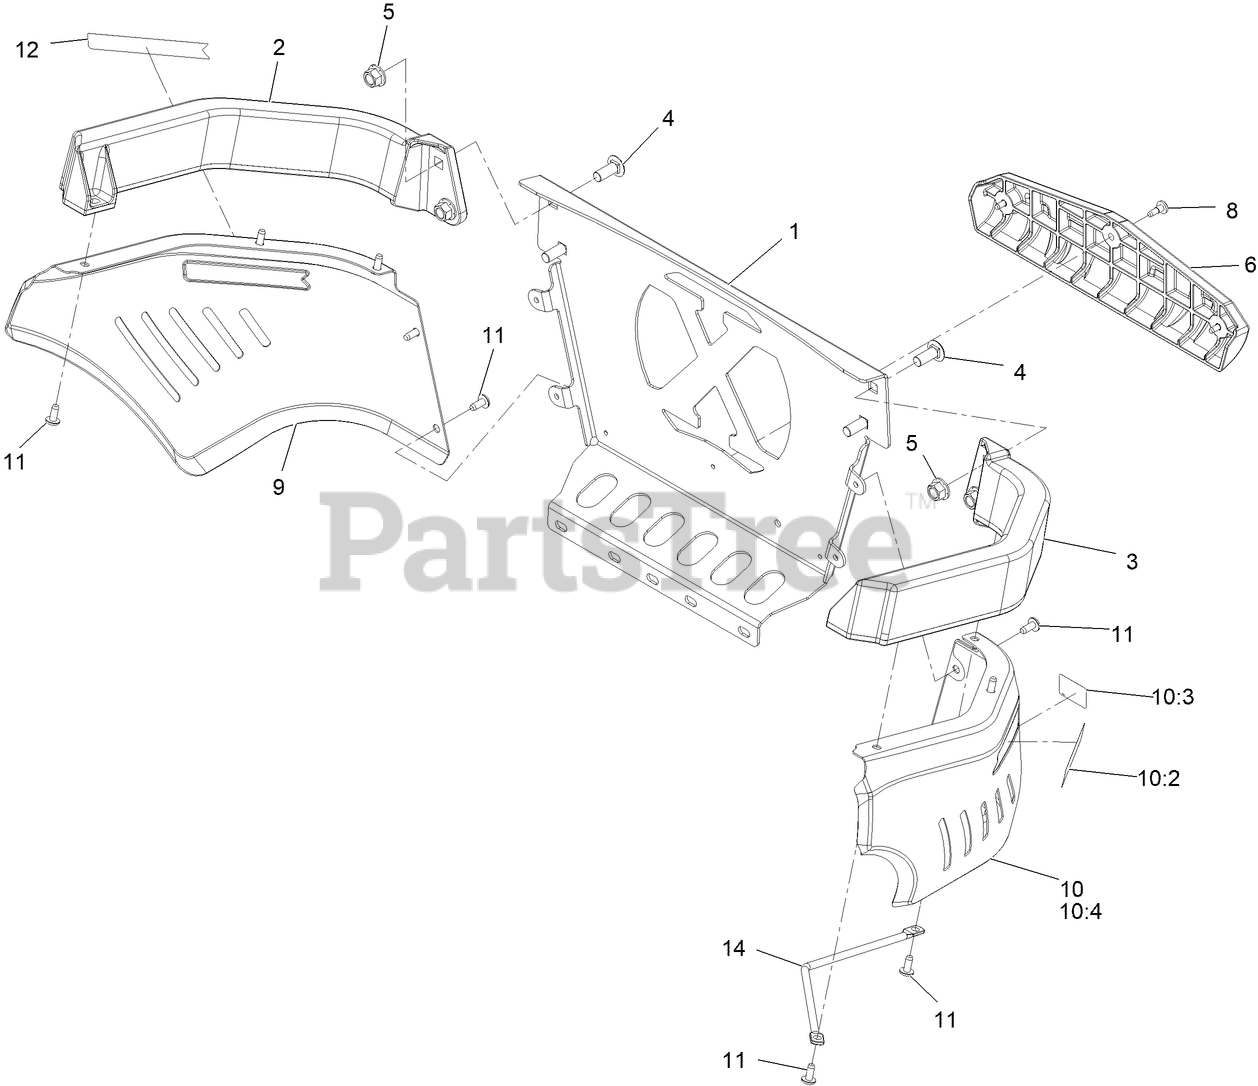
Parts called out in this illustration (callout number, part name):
1	PLATE-REAR
2	SIDE-CAGE, RT
3	SIDE-CAGE, LT
4	SCREW-CARR, SHORT NECK
5	Nut-Lock 1/2-13
6	BUMPER-REAR
8	SCREW-SHOULDER
9	PANEL-QUARTER, RH
10	PANEL-QUARTER, LH ASM
10:2	DECAL-X-SERIES
10:3	DECAL-WARNING
10:4	SHIELD-QUARTER PANEL, LT
11	Screw-HWH 5/16-18 X 3/4 Tf
12	DECAL-X-SERIES
14	GUARD-MUFFLER WIREFORM
